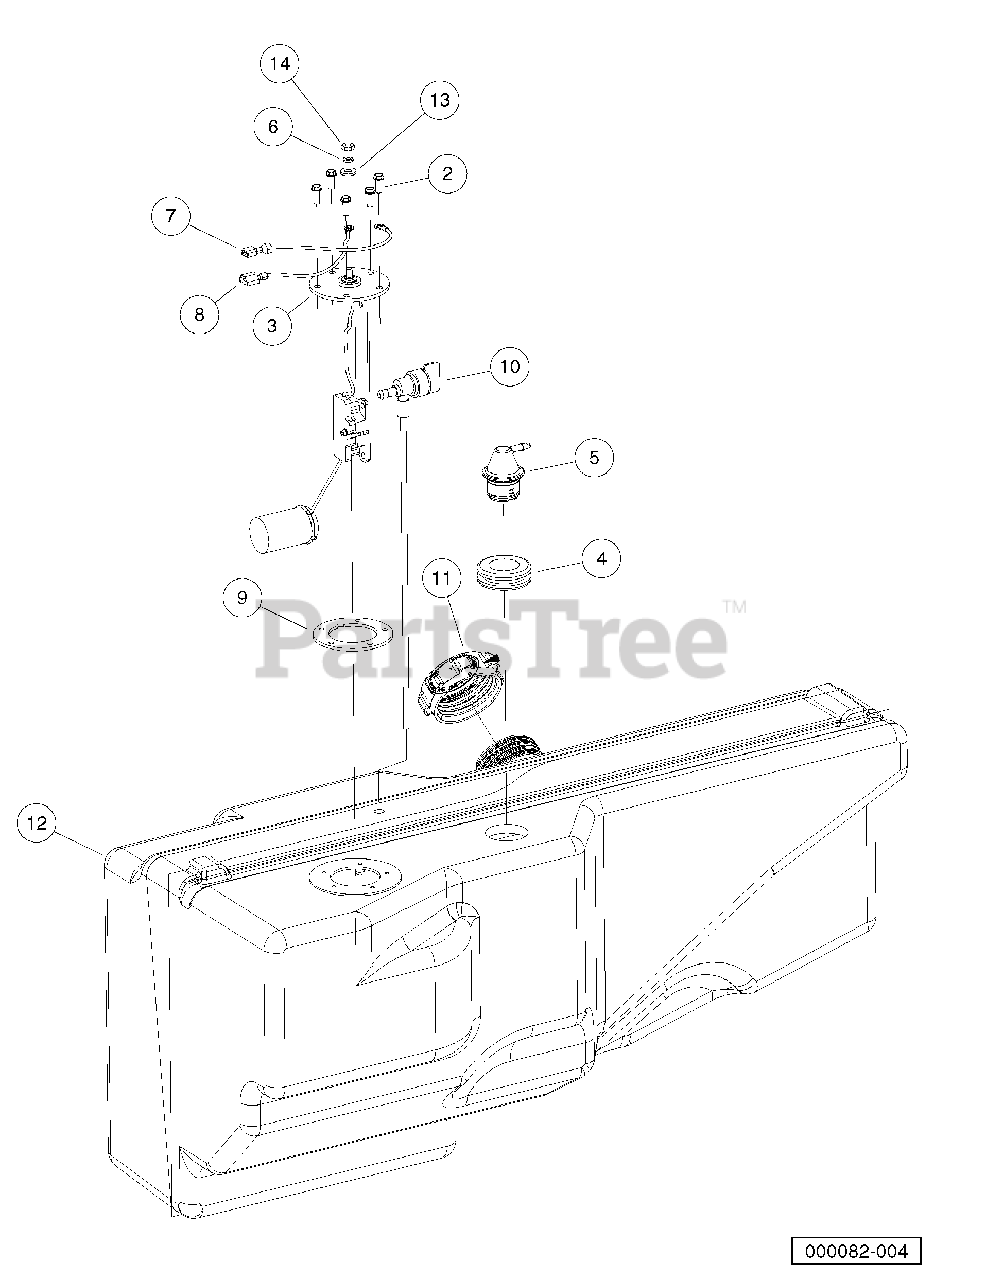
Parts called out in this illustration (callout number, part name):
1	Asm, Tank, Fuel, Gas, 4x4
2	Screw, #10-16 Hex-Head Hi-Lo
3	Sending Unit, Fuel Level
4	Insulation Grommet
5	Vent, Fuel Tank
6	Washer, #10 Split Lock
7	Wire Asm, Blk, 170mm
8	Wire Asm, Org, 170mm
9	Gasket, Rubber
10	Valve, Pickup Tube, Fuel
11	Cap, Fuel Tank, Gasoline
12	Tank, Fuel, Gas, 4x4
13	Washer, #10 Type A Flat
14	Nut, #10-32 Brass Hex
